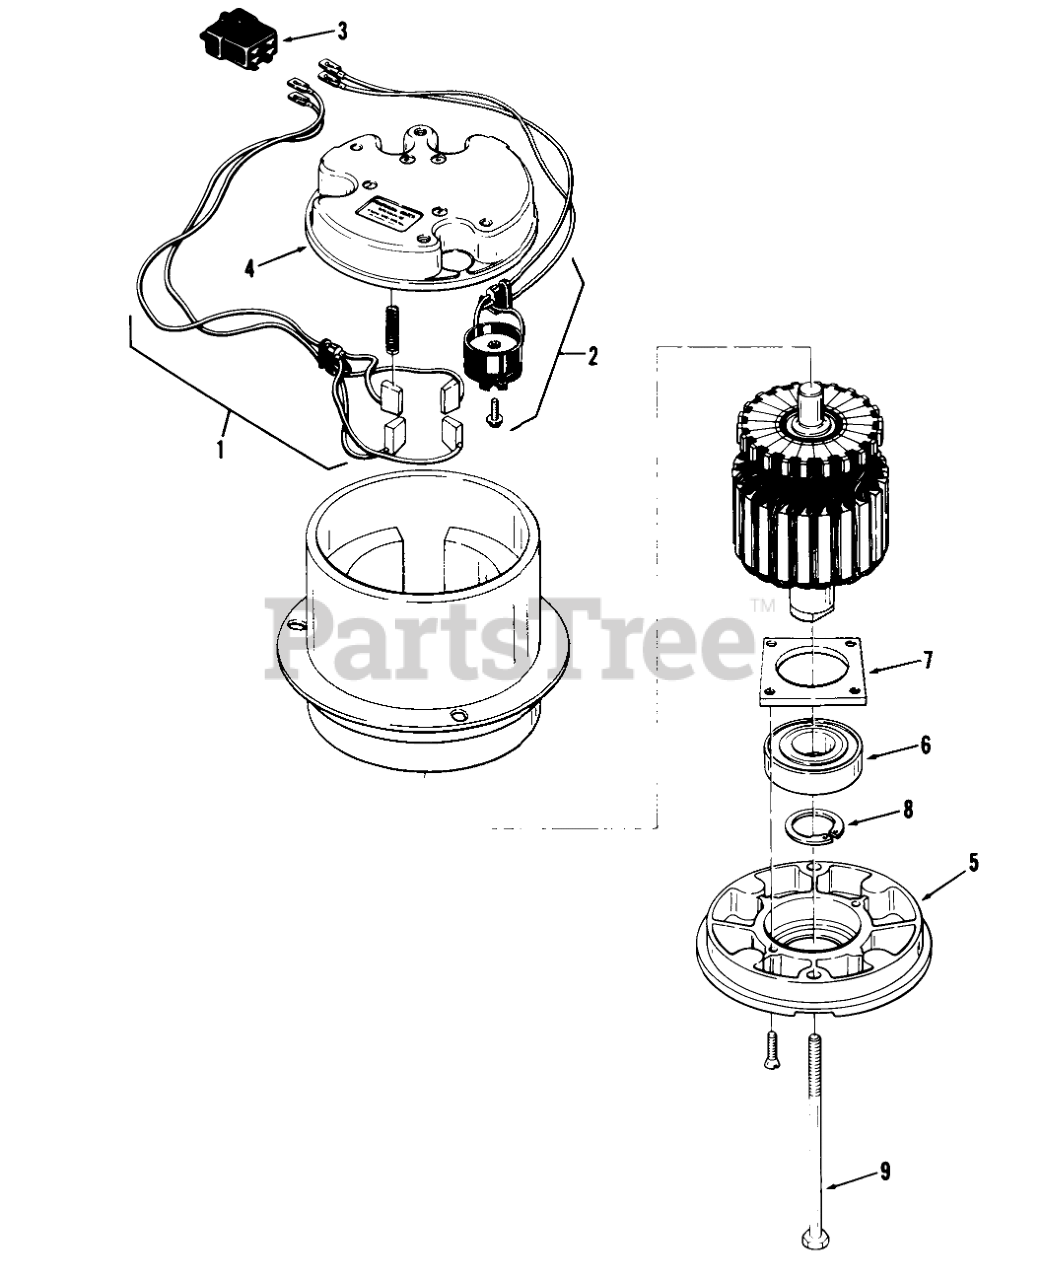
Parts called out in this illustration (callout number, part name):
1	Brush Set (includes springs & connectors)
2	Thermostat (includes grommet & connectors)
3	Connector Body
4	Commutator End Cap (includes bearing & brush holder)
5	Drive End Cap
6	Drive End Bearing
7	Bearing Retainer (includes screws)
8	Retaining Ring
9	Bolt 5/16-18 x 5 1/4
